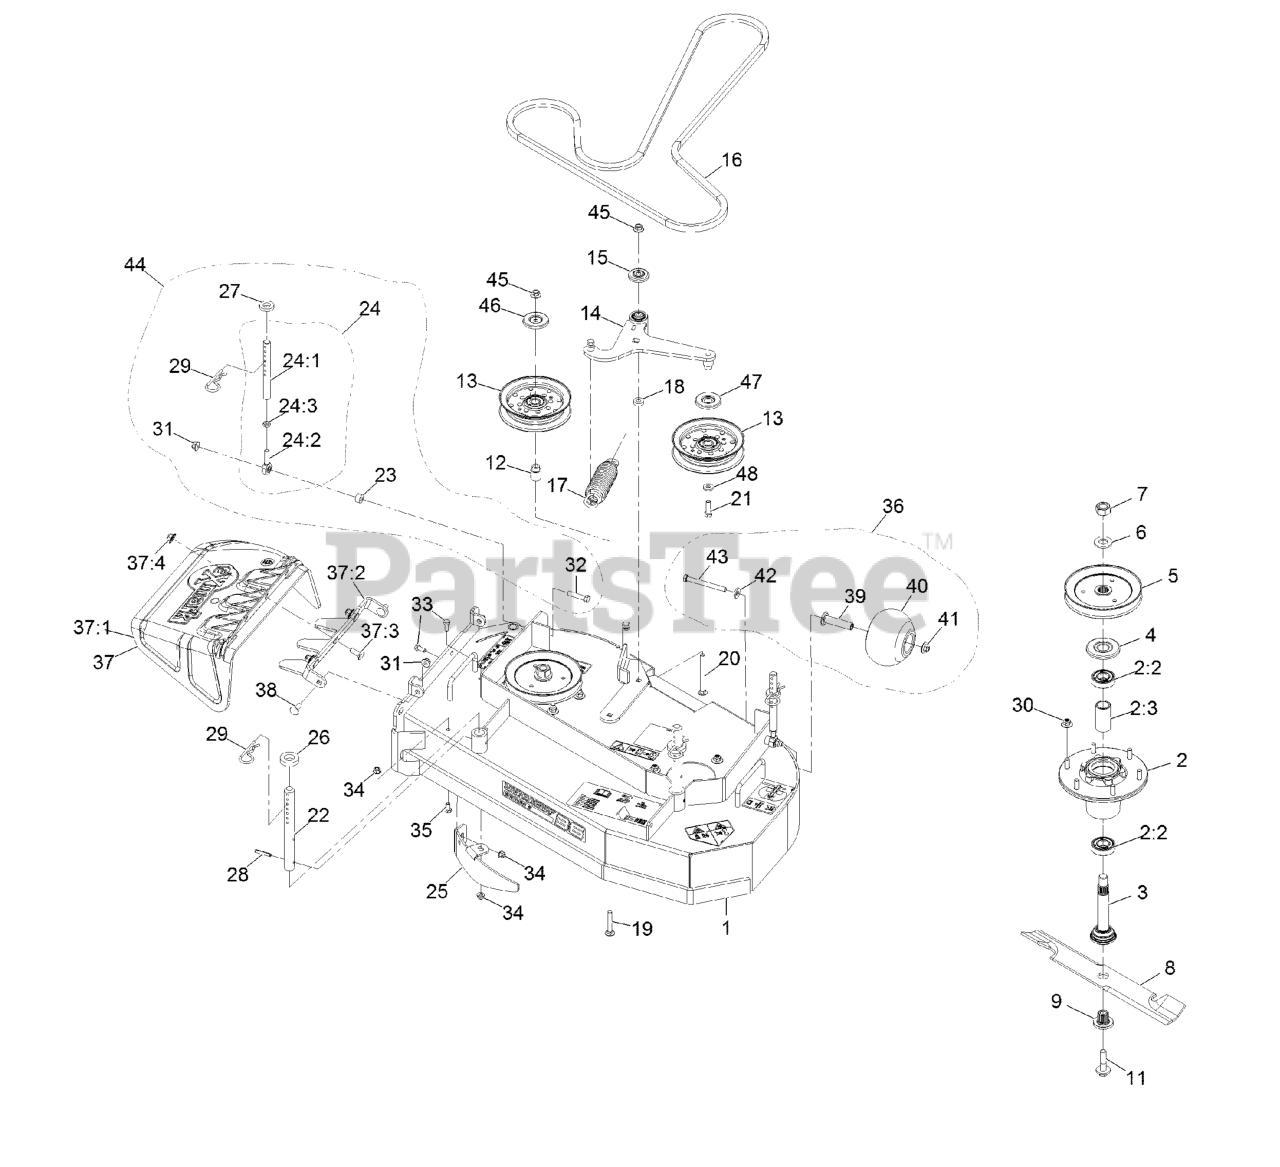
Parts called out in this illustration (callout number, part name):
1	ASM, DECK W/ DECALS, 36
2	ASM-CUTTER HSG WITH BEARINGS
2:2	BEARING-BALL
2:3	SPACER-BEARING
3	ASM-SPINDLE AND SEAL
4	GUARD,BEARING TOP .989
5	SHEAVE,BLADE DRIVE 6.50
7	NUT-HEX
9	BUSHING,SPLINED
11	SCREW,SEMS 1/2-20 X 2.19
12	BUSHING-IDLER
13	IDLER-PULLEY, FLAT
14	ASM-ARM, IDLER
15	GUARD-TOP
17	SPRING-EXTENSION
18	SPACER
19	Bolt-Carriage 3/8-16 X 2 1/4
20	SCREW-CARR
21	SCREW-HH
22	ROD, DECK SUPPORT TTS
24:1	LINK,SUPPORT
24:2	BALLJOINT
24:3	NUT-HJ
25	BAFFLE, DOGLEG
26	SPACER-DECK SUPPORT
29	PIN,HAIR COTTER
30	Nut-Nyloc 3/8-16 Flg
31	NUT-HF, NI
32	SCREW-HH
33	SCREW-HH
34	NUT-HF, NI
35	SCREW-HH
36	KIT, ANTI-SCALP ROLLER
37	ASM, DISCHARGE CHUTE
37:1	CHUTE,DISCHARGE
37:2	BRACKET, DISCHARGE CHUTE
37:3	SCREW-CARR
37:4	Nut-Nyloc 3/8-16 Flg
38	SCREW-CARR
39	AXLE, ROLLER
40	ROLLER-SCALP, ANTI
41	Nut-Nyloc 3/8-16 Flg
42	WASHER-BELLEVILLE
43	SCREW-HH 3/8-16 X 3 3/4 GR 8
44	KIT,SUPPORT LINK W/PIN
46	SHIELD-DUST
47	SHIELD-GUARD, DUST
